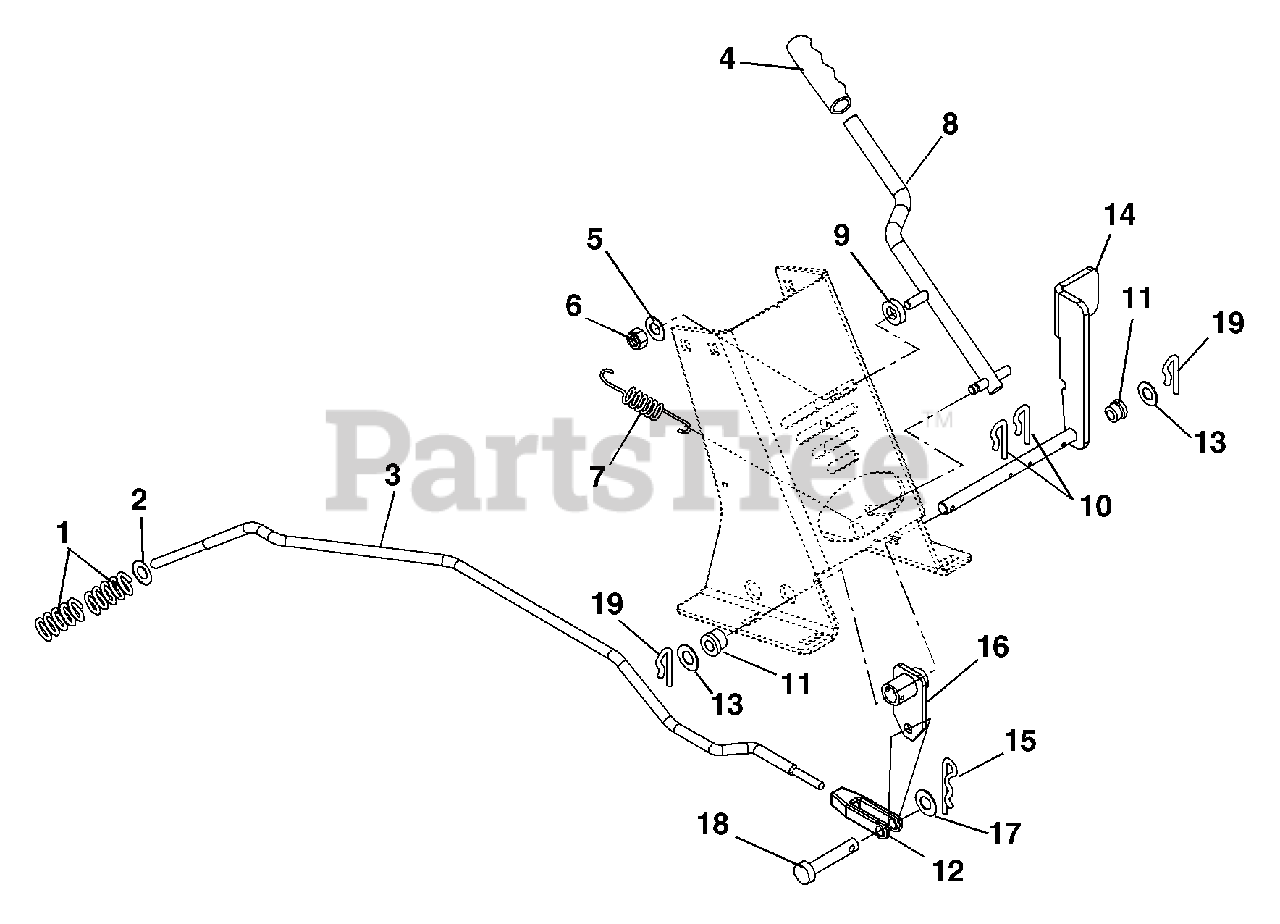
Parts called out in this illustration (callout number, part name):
1	Spring, Compression .063 x .53 x 1.19
2	Washer, Flat Steel .39 x .75 x .125
3	Rod, Brake Rear Engine Rider Hydro
5	Washer, Flat Steel .38 x .875 x .083
6	Nut, Locking Top Flange .38-16
7	Spring, Tension .048 x .44 x 2.12
8	Weldment, Parking Brake
9	Bushing, Flange .406 x .88 x .27 x .140 Grade 2
10	Pin, Spring Clip
11	Bushing, Flange .515 x .75 x .745 x 1.00 Nylon
12	Yoke, .312-24 x 2.25
13	Washer, Flat Steel .505 x 1.00 x .062
14	Weldment, Brake Pedal
15	Pin, Hair
16	Brake Rod Arm and Hub
17	Washer, Flat Steel .38 x .87 x .179
18	Pin, Clevis .312 x .822
19	Clip, Spring
